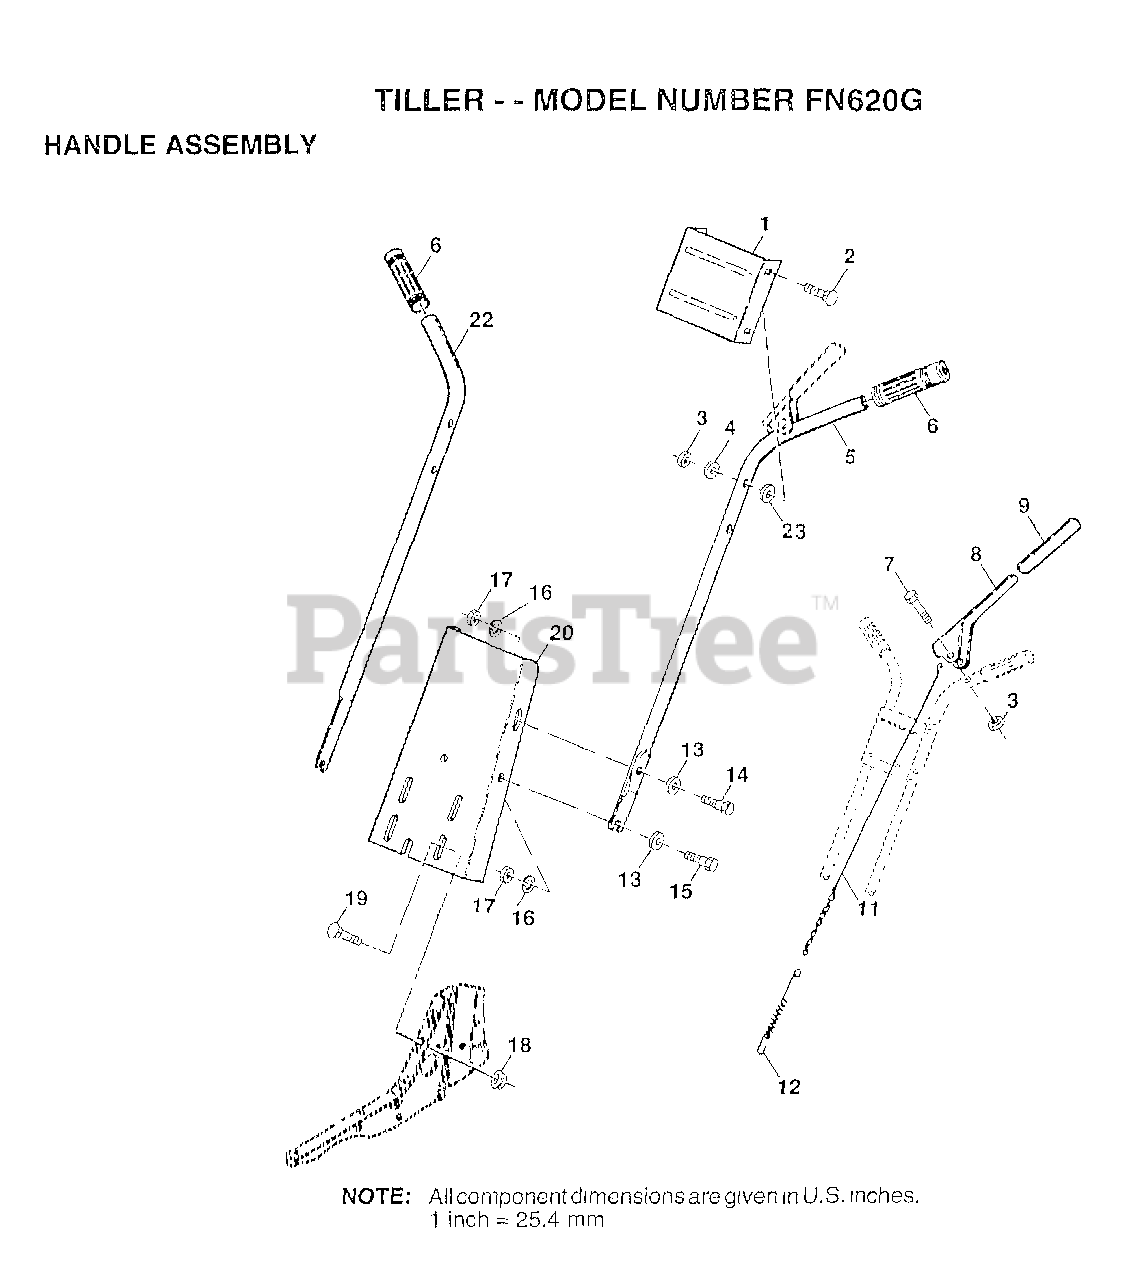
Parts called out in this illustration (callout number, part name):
1	HANDLE BRKT
2	BOLT
4	WASHER
5	HANDLE LH
7	BOLT.HEX.5/16-1.5
8	LEVER.CONTROL.TINE
9	GRIP T
12	SPRING EXT TI
13	WASHER
15	BOLT
16	LOCKWASHER
17	NUT.HEX.5/16-18
18	NUT
19	BOLT
20	PANEL. HANDLE
22	HANDLE RH
23	WASHER
